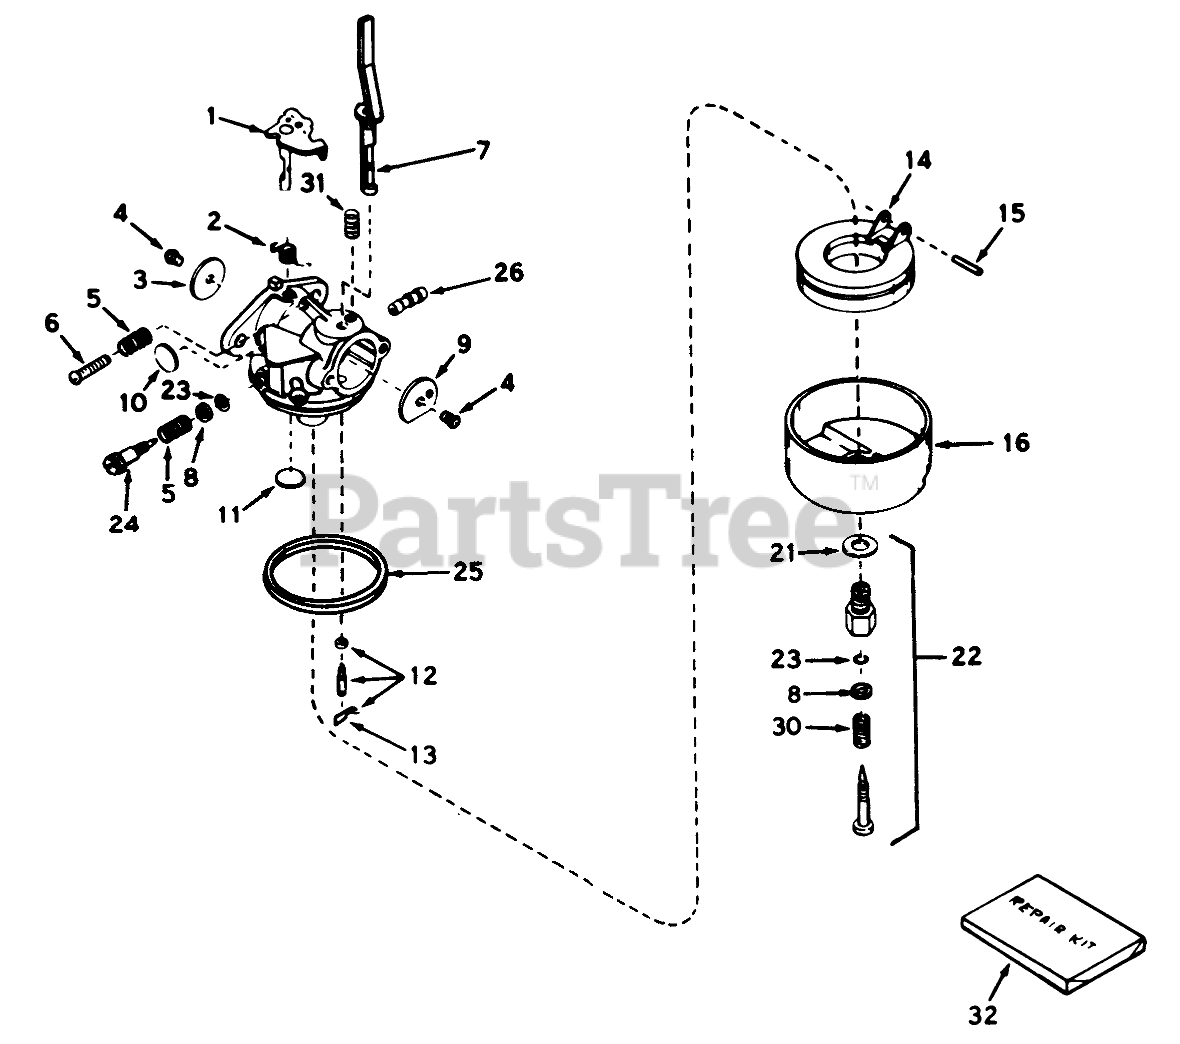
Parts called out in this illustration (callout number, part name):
1	Shaft/Lever-Throttle
2	Spring, Return
3	Shutter-Throttle
4	Screw-Shutter
5	Spring-Tension
6	Screw-Throttle Crack Screw / Idle Speed
7	Shaft & Lever Assy., Choke
9	Shutter-choke
10	Plug-Welch, Idle Mixture Well
11	Plug-Welch, Atmospheric Vent
12	Inlet Needle, Seat & Clip Assy. (Incl. Ref. #13)
13	Clip-Spring
14	Float
15	Shaft-Float
16	Bowl-Float (no drain)
21	Washer-Bowl Nut
22	Adjustment Screw Assy., Main (Incl. Ref. #8, 21, 23 & 30)
23	"O"Ring
24	Screw, Idle Adj.
25	O Ring-Bowl, Float
26	Fuel Fitting
31	Spring-Positioning, Choke
32	Kit-Repair
